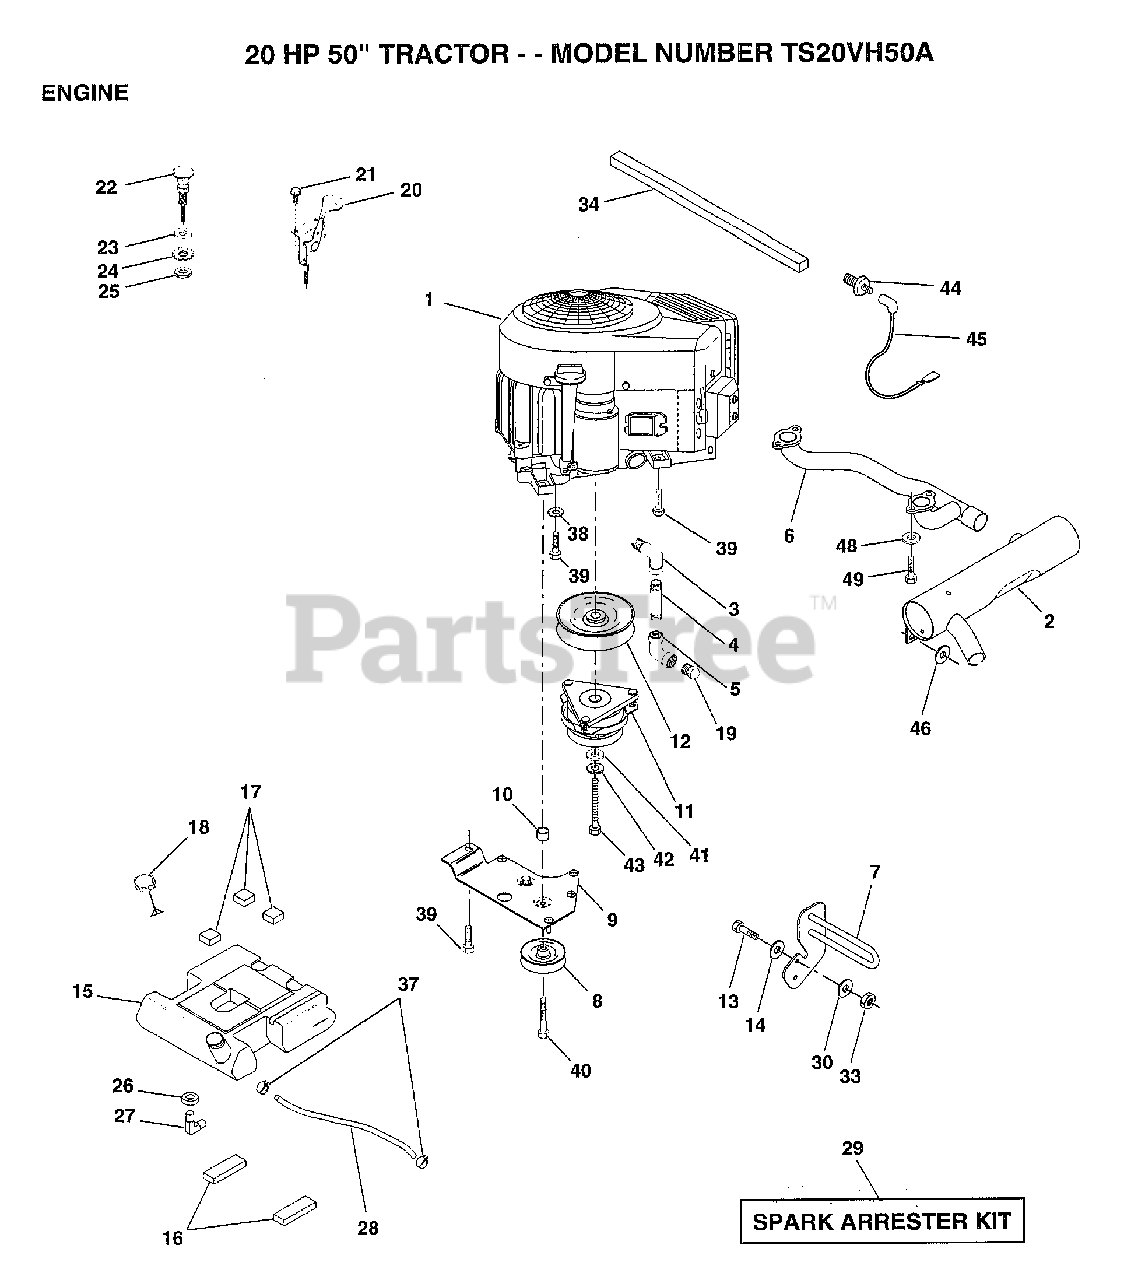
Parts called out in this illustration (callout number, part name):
3	STREET ELBOW LT
4	PIPE NIPPLE
5	ELBOW
6	PIPE.EXHAUST.B&S
10	BUSHING.
12	PULLEY.ENGINE.VGT
13	"BOLT,HEX"
14	WASHER
16	PAD IDLER TI
17	PAD-SPACER LT
18	CAP ASM FUEL
19	PLUG T
21	SCREW LT
23	WASHER
24	LOCKWASHER
26	BUSHING OUTLET T
27	STEM.TANK.FUEL
29	SPARK ARREST KIT
30	WASHER T
32	SCREW LT
33	NUT
34	FOAM-STRIP LT
35	LOCKWASHER
36	SCREW
37	HOSE CLAMP
38	LOCKWASHER
39	SCREW LT
40	SCREW.3/8-16X3.25
41	WASHER
42	LOCKWASHER
44	SWITCH OIL KOHLER
45	WIRE.LEAD.SENTRY
46	WASHER HYT
48	LOCKWASHER
49	BOLT.HD.SOCKET.
